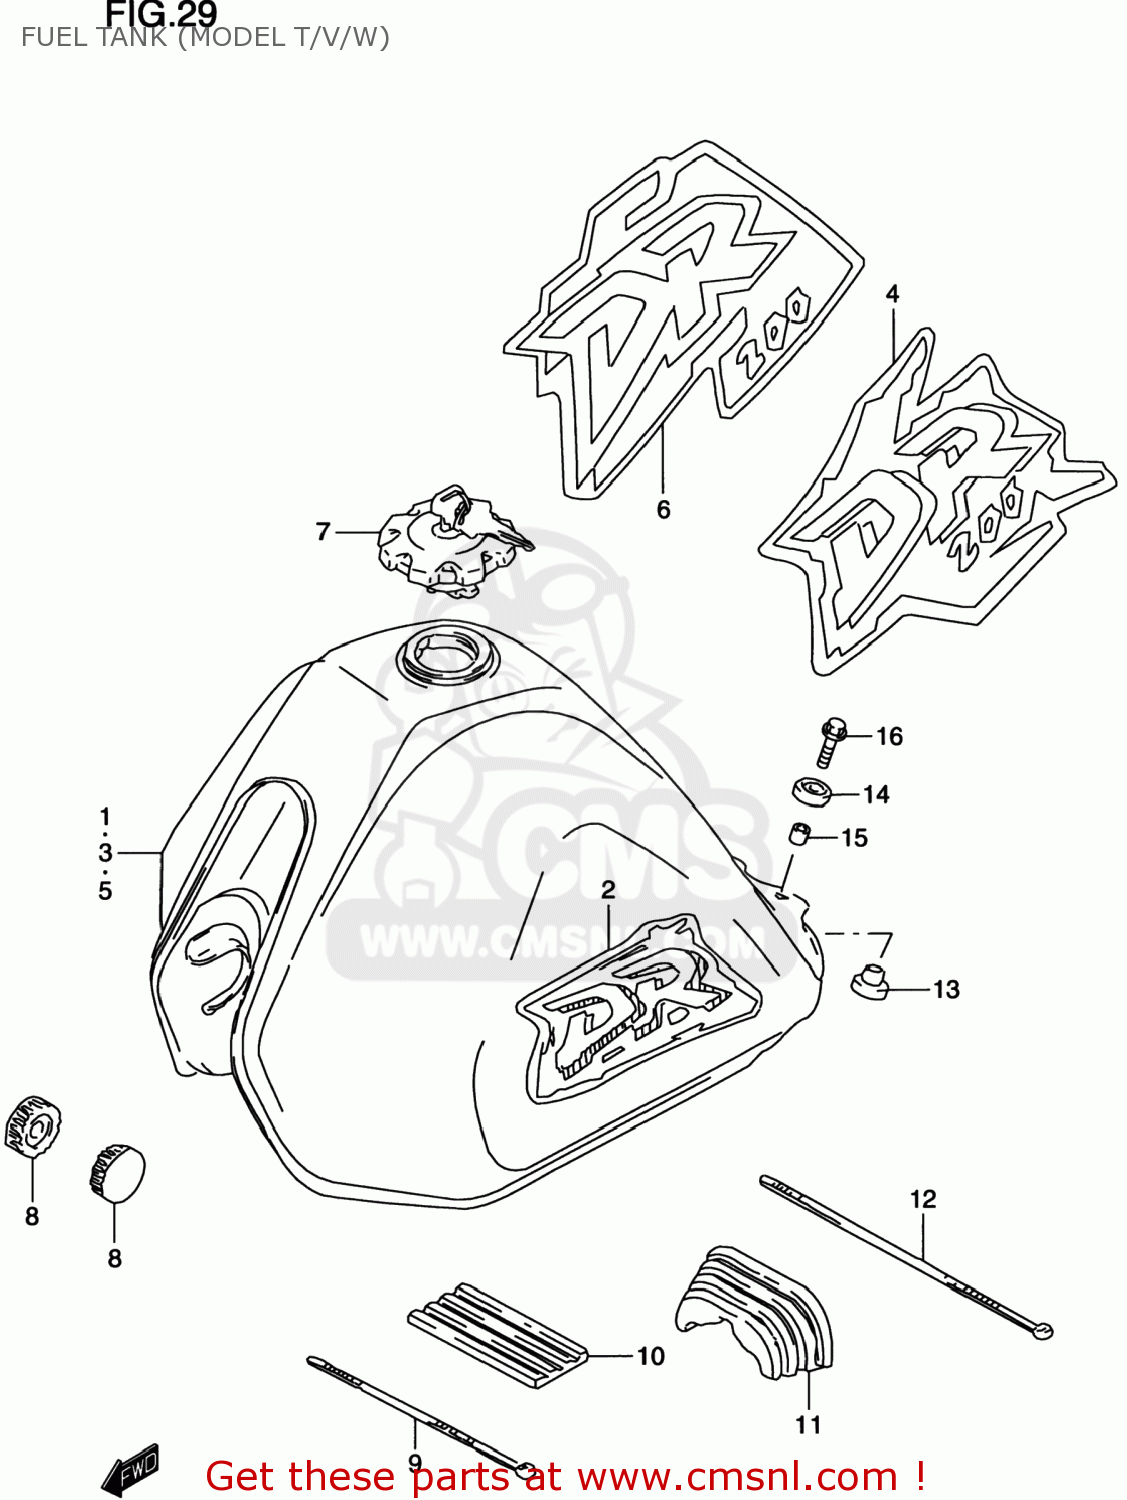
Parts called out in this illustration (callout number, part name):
1	TANK ASSEMBLY,FUEL
2	EMBLEM SET,FUEL TANK
3	TANK ASSEMBLY,FUEL (WHITE)
4	TAPE SET,FUEL TANK
5	TANK ASSEMBLY,FUEL
6	TAPE SET,FUEL TANK
7	CAP SET,FUEL TANK
8	CUSHION
9	CLAMP(L:250)
10	CUSHION,FUEL TANK UPR FR
11	CUSHION,FUEL TANK RR
12	CLAMP(L:300)
13	CUSHION
14	CUSHION
15	SPACER(6.5X9X18)
16	BOLT
